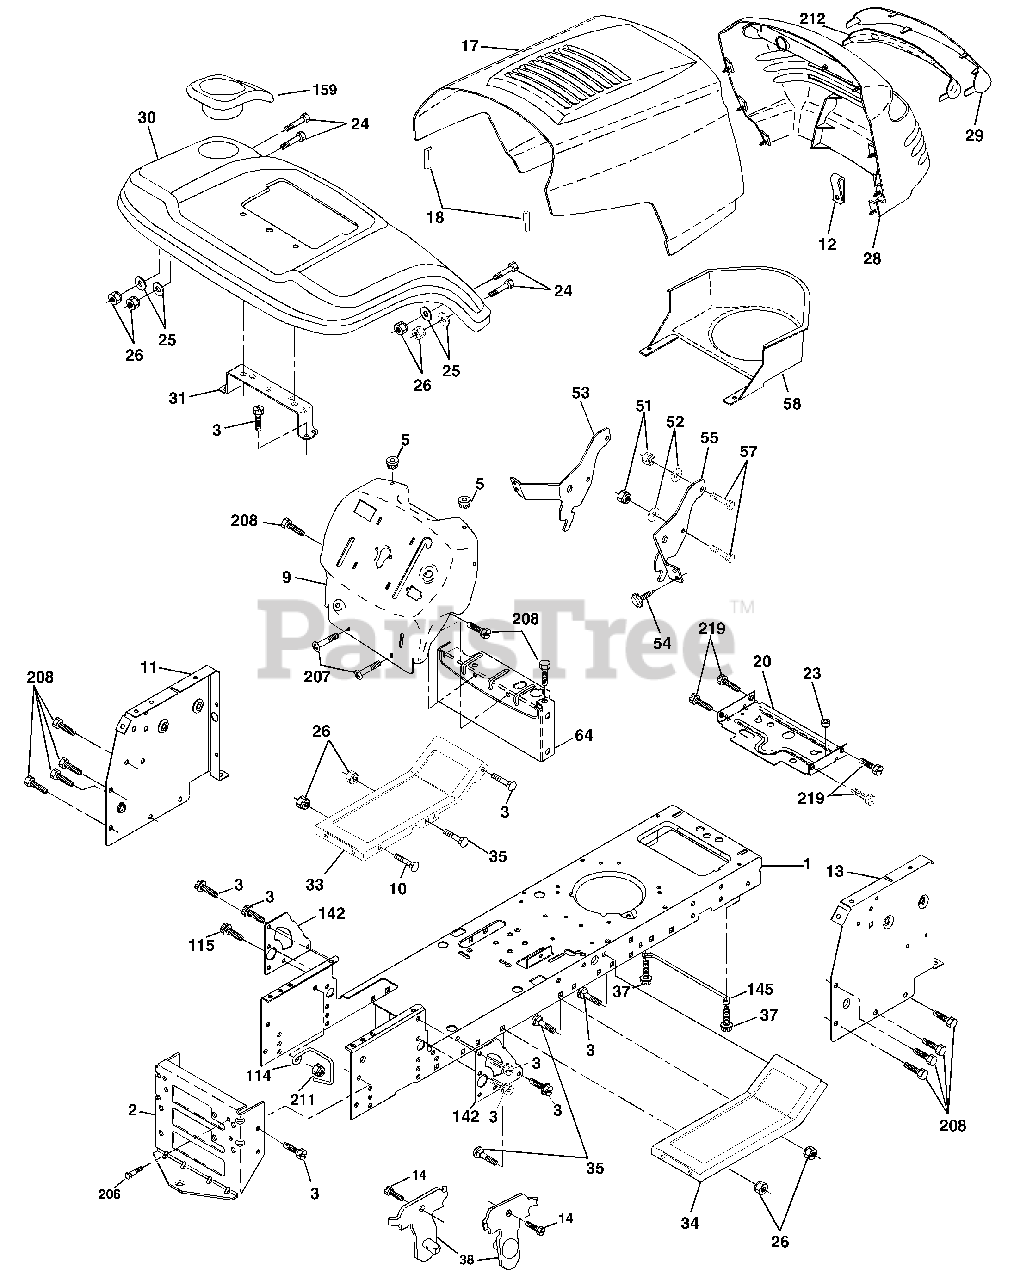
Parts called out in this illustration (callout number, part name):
1	Chassis
2	Drawbar
3	Screw 3/8-16x.75
5	Bumper Hood/Dash
9	Dash P/L
10	Bolt Carriage 3/8-16 x 1
11	Panel Dash Lh
12	Clip Tinnerman
13	Panel Dash Rh
14	Screw Thdrol 3/8-16 x 1-1/4
17	Hood LT/PL
18	Bumper Hood
20	Plate Mtg Battery Fuel Tank Fr
23	Bushing
24	Bolt Fin Hex 3/8-16 x 1 Gr 5
25	Washer 13/32 X 13/16 X 12 Ga
26	Nut Lock Hex W/Ins 3/8-16 Unc
28	Grille LT/PL
29	Lens LT/PL
30	Fender Footrest STLT Pnt
31	Bracket Support Fender
33	Footrest Pnt Lh
34	Footrest Pnt Rh
35	Bolt Rdhd Sht Sqnk 3/8-16 x 3/4
37	Screw Thdrol 6/16-18 x 1/2 TYT
38	Bracket Asm. Pivot Mower Rear
51	Nut Lock Hex W/Ins 1/4-20
52	Washer 9/32 x 7/8 x 16 Ga.
53	Bracjet Grukke Lh
54	Screw Hex Wshd 8-18 x 7/8
55	Bracket Grille Rh
57	Bolt Hex 1/4-20 x 3/4
58	Duct Air
64	Dash Lower STLT
114	Keeper Belt Rear Lh
115	Screw 3/8-16 x 1-1/4
142	Plate Reinforcement STLT
145	Rod Pivot Chassis/Hood
159	Cupholder
206	Bolt Shoulder 5/16-18
207	Screw Thdrol 5/16-18 x 1/2
208	Screw Thdrol 3/8-16 x 1/2
211	Nut Hex Flange Lock
212	Insert Lens Reflect P/L LT
219	Screw 5/16-18 x 3/4
